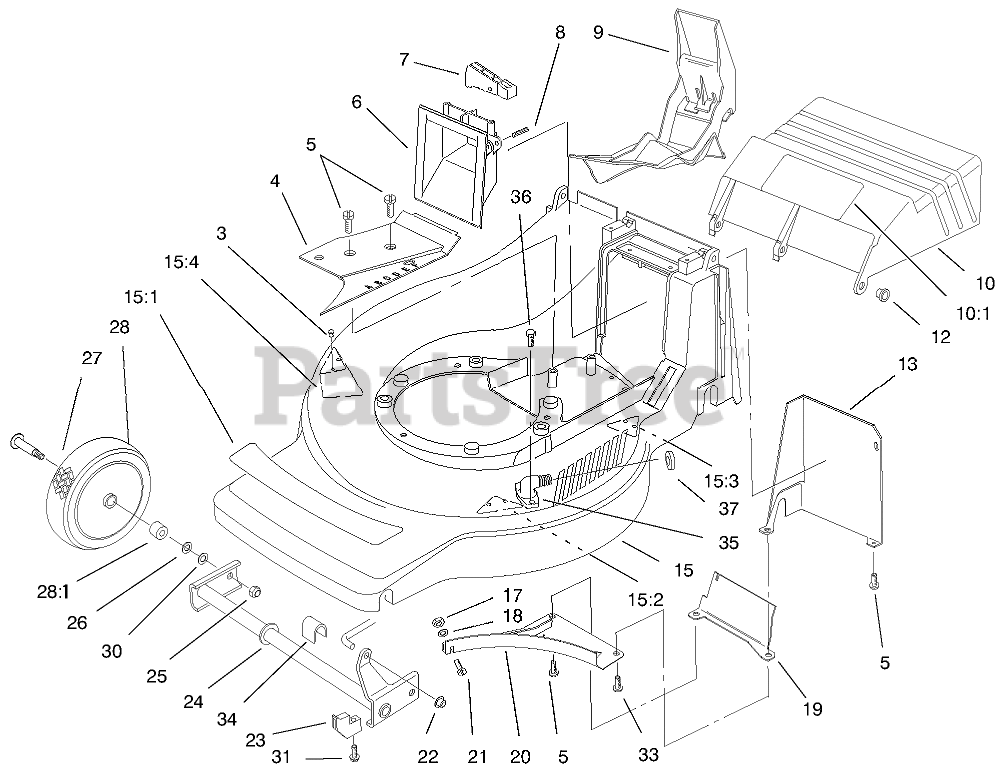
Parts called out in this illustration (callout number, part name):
1	Decal-Deck
4	COVER - BELT
5	SCREW-RH
6	GRIP-LOWER
7	TRIGGER-HEIGHT OF CUT
8	PIN-SPIRAL
10	DISCHARGE DOOR ASM
10:1	DECAL-DANGER
12	BUSHING-DOOR
13	COVER-SHIELD
15	DECK ASSEMBLY-43CM (SERVICE)
15:1	KICKER
15:2	KICKER
15:3	KICKER
15:4	SCREW-PPH
17	NUT-LOCK, NI
18	WASHER-FLAT
19	BAFFLE-BAGGER, REAR
20	BAFFLE
21	SCREW-PPH
22	NUT-PUSH
23	RETAINER-AXLE
24	AXLE-FRONT
25	Nut-Lock
26	WASHER
27	Bolt-Wheel
28	WHEEL-FRONT
28:1	BUSHING
30	WASHER-SPRING
31	SCREW-RETAINER
33	SCREW-BAFFLE
34	CAP-AXLE, FRONT
35	FITTING-WASHOUT
36	SCREW-HWH
37	O-RING
